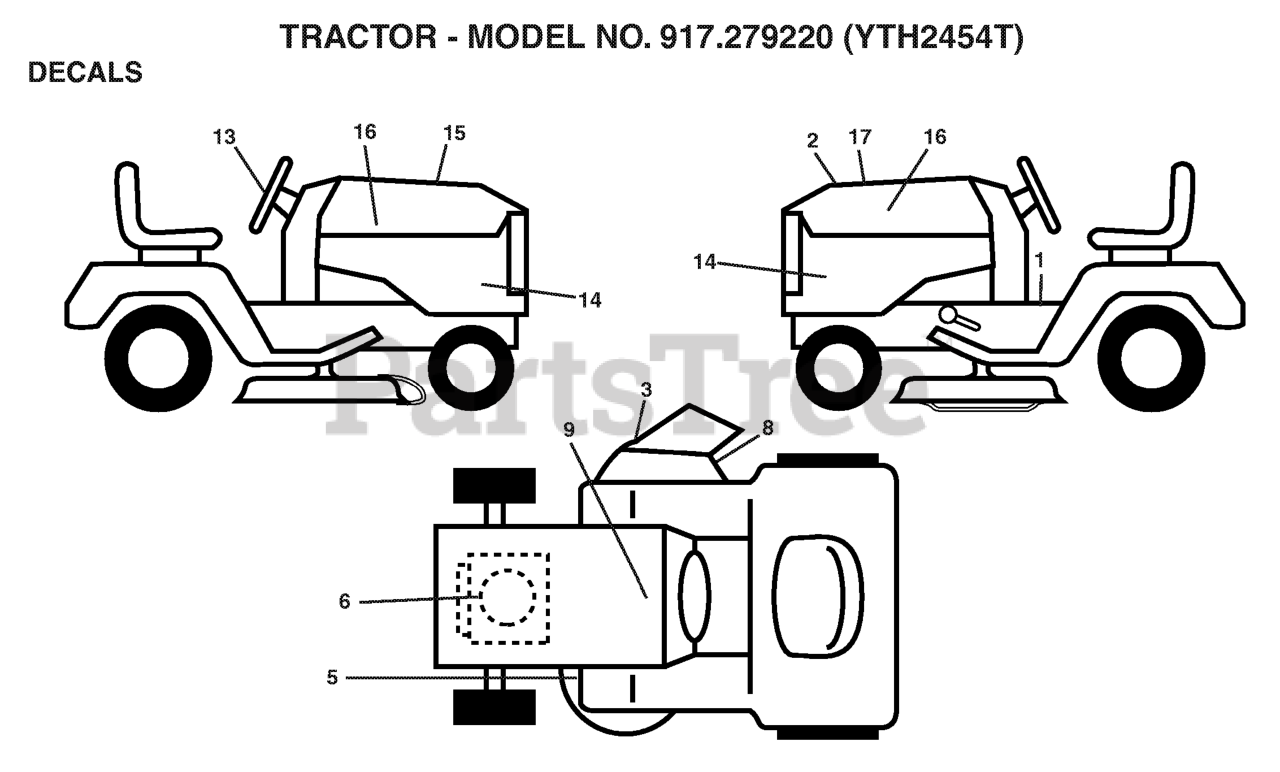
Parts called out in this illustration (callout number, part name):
1	DECAL.FENDER.OPER.TEX.
2	DECAL.HOOD.TOP.INSERT.
3	DECAL.WARN.KEEP.HAND.AWAY
5	DECAL CLUTCH/BRAKE
8	DECAL.MOWER.SCH.48/54
9	DECAL BTRY SYMBOLS
13	DECAL.STEERING.HUSQ.BLUE
14	DECAL.PANEL.SD.YTH2454
15	DECAL HOOD CUST. RESP.
16	DECAL.HOOD.NAMELOGO.HUSQ
17	DECAL.RPL.B&S.24
